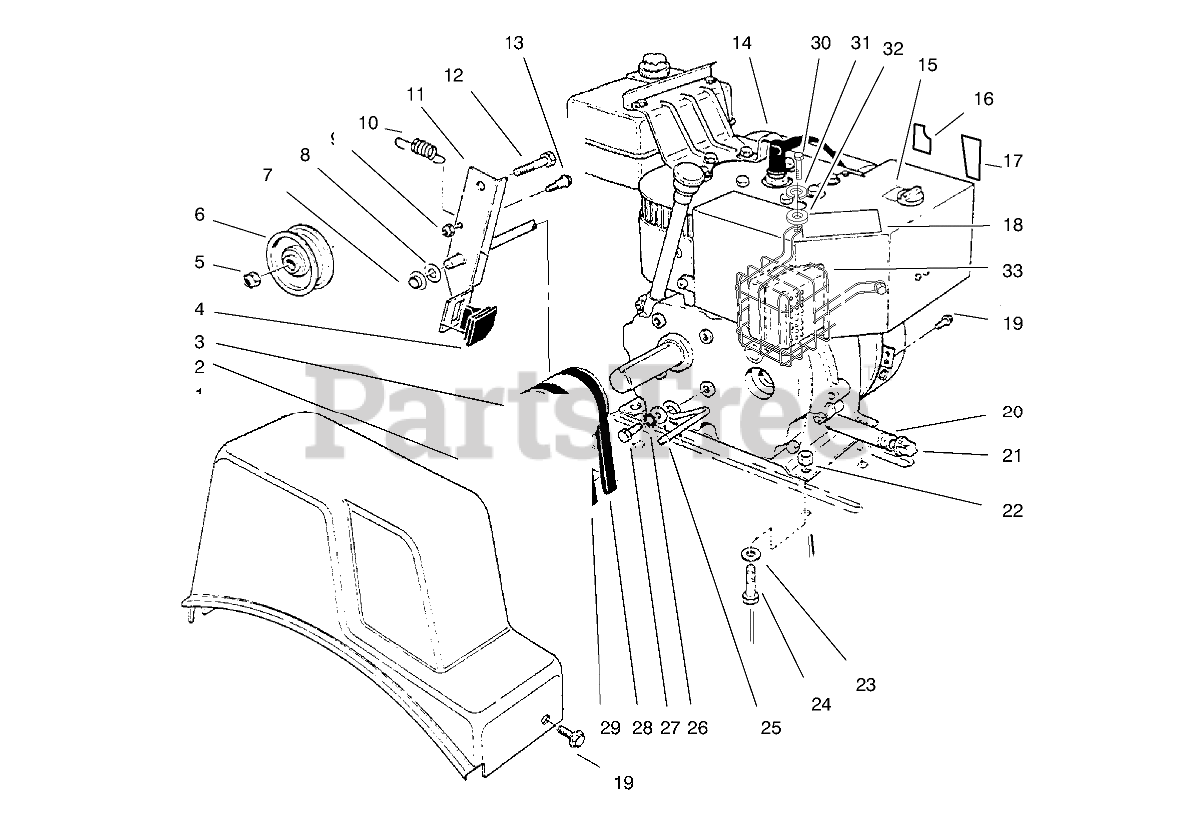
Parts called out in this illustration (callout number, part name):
1	COVER-BELT
2	SCREW-SPECIAL
3	PULLEY-ENGINE
4	PAD-BRAKE
5	NUT-LOCK, NI
6	PULLEY-IDLER
7	RETAINER-PUSH ON
8	WASHER-FLAT
9	NUT-LOCK, NI
10	SPRING
11	Auger Clutch (Incl. Ref. #4)
12	SCREW-HH
13	BOLT-SHOULDER
15	DECAL-CHOKE
16	DECAL - PRIMER
17	THROTTLE DECAL, INT'L
18	DECAL-WARNING, HOT SURFACE
19	SCREW-HWH
20	PIPE-NIPPLE
21	CAP-PIPE
22	NUT-LOCK, NI
23	WASHER-PLAIN
24	SCREW-HH
25	RETAINER-BELT
26	WASHER-LOCK
27	SCREW-HH
28	V BELT-3L, TRACTION
29	V-BELT
30	Screw
31	Washer-Lock
32	Washer-Flat
33	Guard-Muffler
